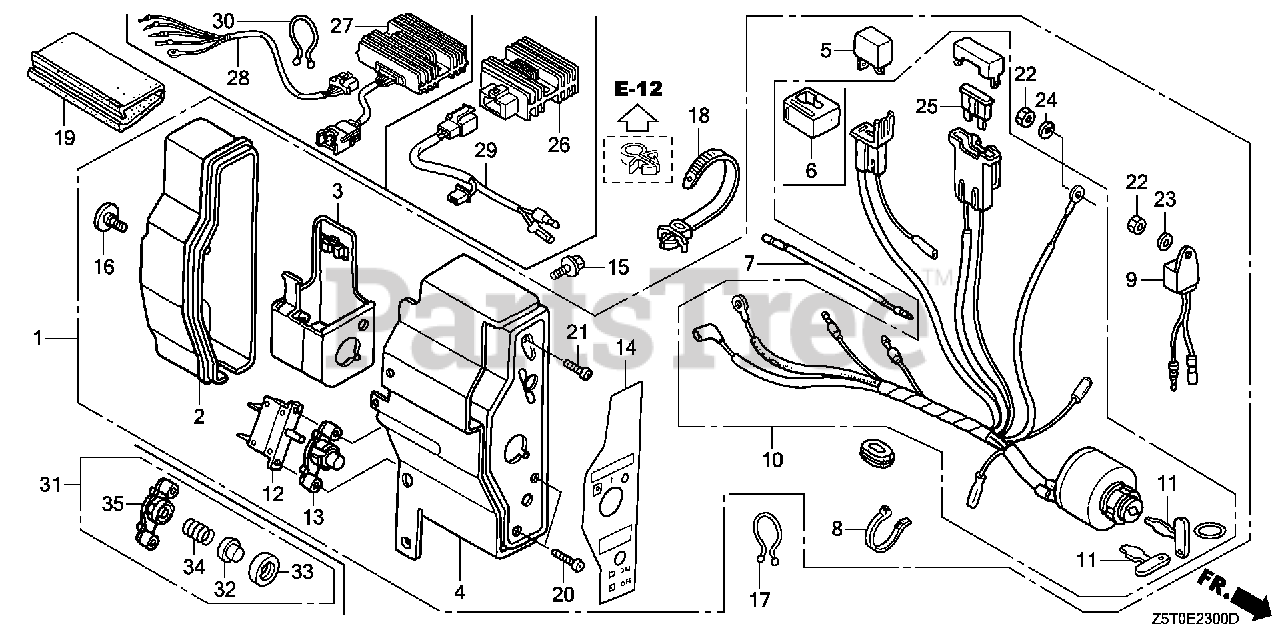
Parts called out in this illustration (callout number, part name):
1	BOX ASSY., CONTROL (3A) *NH1* (BLACK)
1	BOX ASSY., CONTROL (3A) *R280* (POWER RED)
2	CASE, CONTROL
3	BRACKET, CASE MOUNTING
4	PANEL, CONTROL *R280* (POWER RED)
4	PANEL, CONTROL *NH1* (BLACK)
5	RECTIFIER ASSY., SILICON (SHINDENGEN)
6	SUSPENSION, CONNECTOR
8	BAND
10	SWITCH ASSY., COMBINATION (3A-CHARGE)
11	KEY
12	PROTECTOR, CIRCUIT (3.5A)
13	LENS ASSY., PROTECTOR
14	MARK, CONTROL BOX (EXTERNAL)
15	BOLT, FLANGE (6X12) (CT200)
16	SCREW, SPECIAL (6X12)
17	CLIP, PURSE LOCK
18	STRAP, CABLE (118MM) *NH1L* (Honda Code 1170653). (BLACK)
19	TUBE, FASTENER (30)
20	SCREW, PAN (3X12)
25	FUSE, BLADE (15A)
